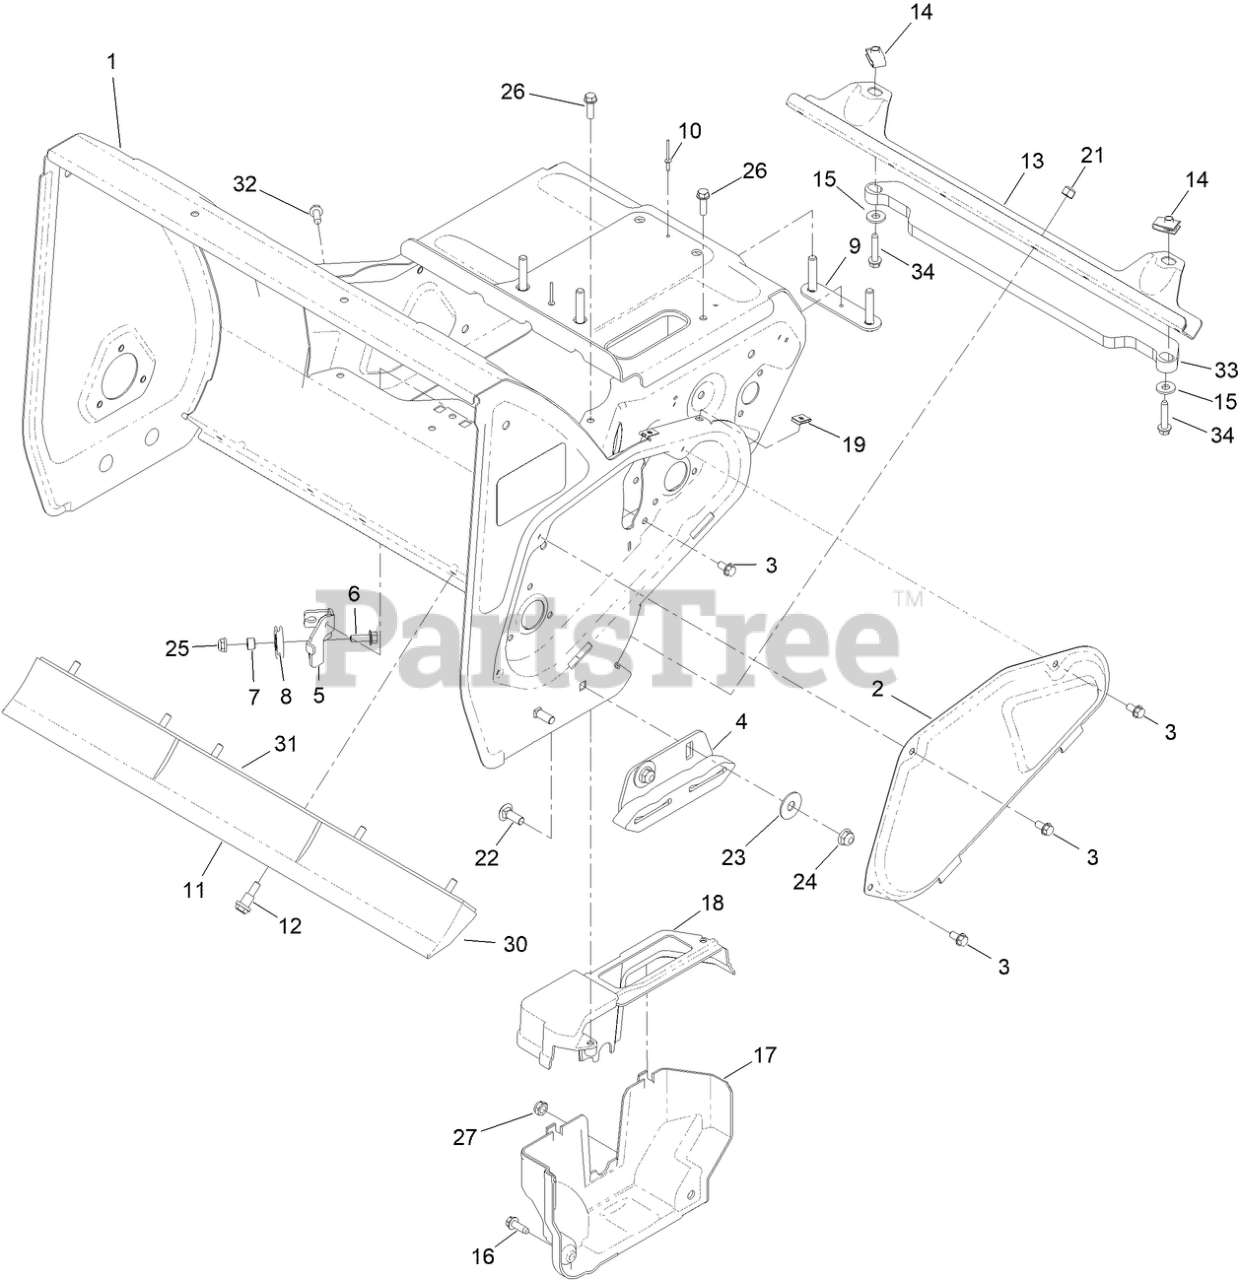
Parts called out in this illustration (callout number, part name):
1	FRAME ASM
2	COVER-BELT
3	SCREW-HWH
4	SKID ASM
5	BRACKET-CABLE
6	SCREW-HHF
7	SPACER-BLADE, ROTOR
8	CABLE-PULLEY
9	PLATE-STUD, REAR
10	RIVET
11	SCRAPER ASM
12	BOLT-SHOULDER
13	SUPPORT-FRAME, LOWER
15	WASHER-FLAT
16	SCREW-HWHTF
17	COVER-BELT, LOWER
18	COVER-BELT, UPPER
19	NUT-SPEED
21	NUT-HEX
22	BOLT-CARR
23	WASHER-FLAT
24	NUT-HF
25	NUT-HF
26	SCREW-PLASTITE, HWH
27	NUT-HEX
30	BLADE-SCRAPER
31	FOAM-SCRAPER
32	SCREW-HWH
33	PLATE-WEIGHT
34	SCREW-HWHTF
